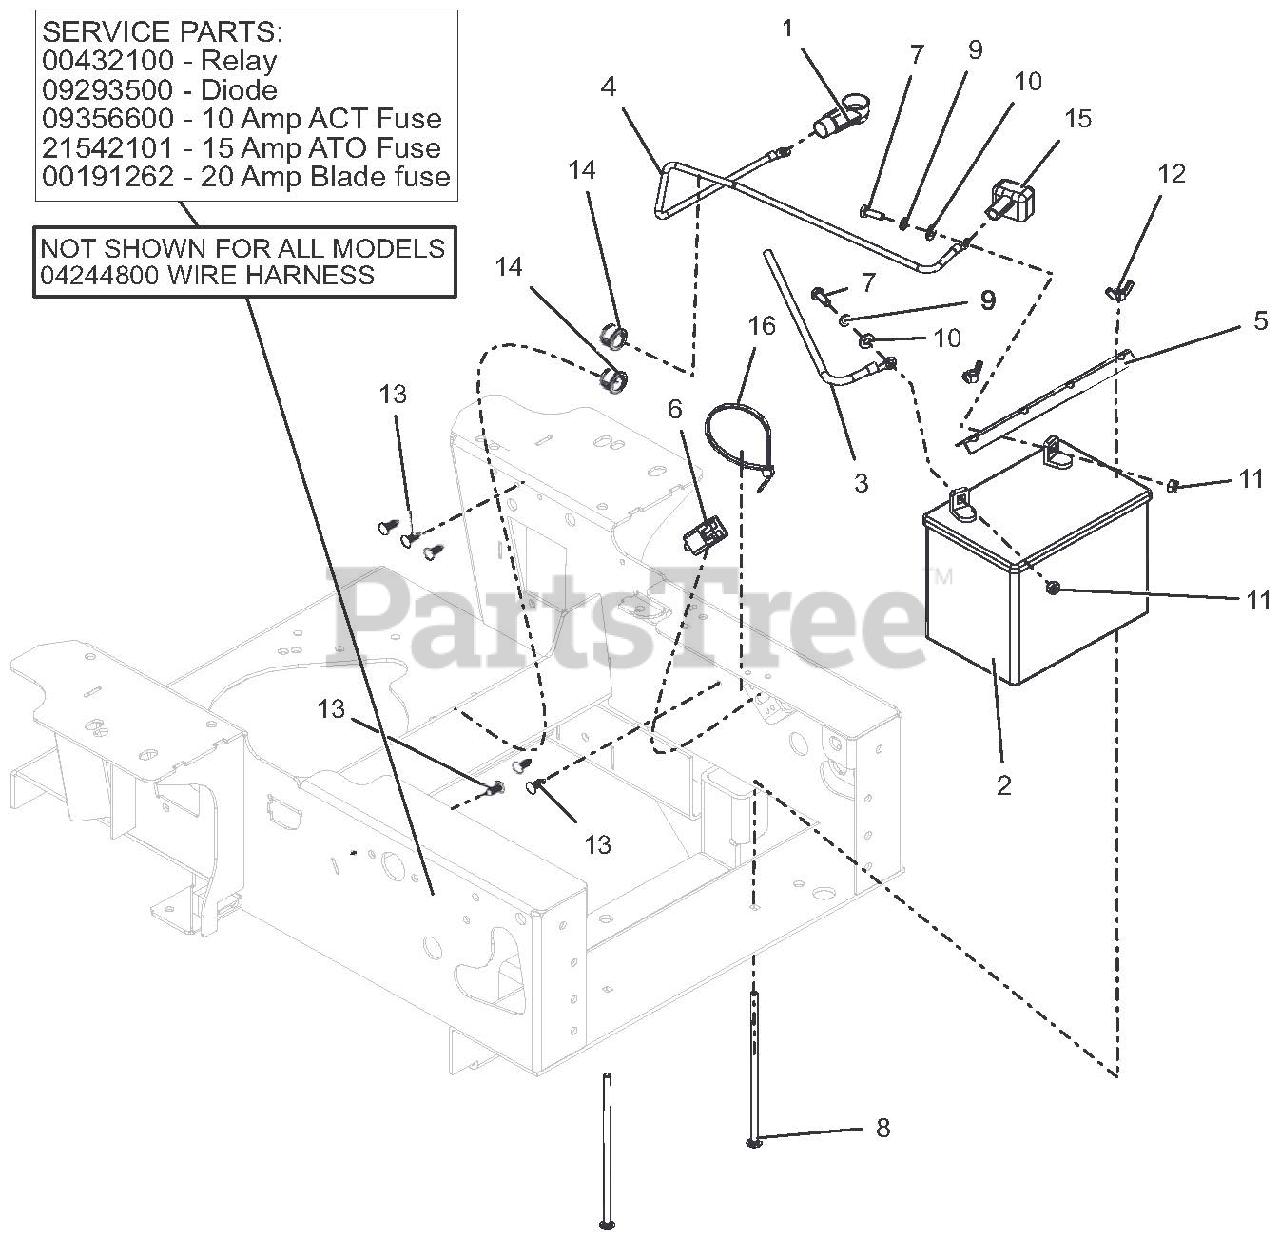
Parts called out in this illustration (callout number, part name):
1	BOOT, .65 ID POS
2	BATTERY, 300 CCA 10U1L
3	CABLE, GROUND 22.00"
4	CABLE, STARTER .31 X 23.00 X .31
5	HOLD DOWN - BLK
6	SWITCH, SNAP IN -N.O./N.O
7	BLT-HEX .25-20X.75 GR5 YWZC
8	BLT-RDHDSQNK .25-20X7.50 G2 YWZC
9	WSHR-LK .25X.062 REG YWZC
10	WSHR-FL-STL.281X.62X.065 YWZC
11	NUT-HEX .25-20 YWZC
12	NUT-LOCKING WING 1/4-20
13	RIVET, .25 NYLON PANEL
14	BUSH, PANEL SNAP .687X.875X.56
15	INSULATOR
16	CABLE, TIE 5.50 LG
17	RELAY
18	DIODE
19	10 AMP ACT FUSE
20	15 AMP ATO FUSE
21	20 AMP BLADE FUSE
